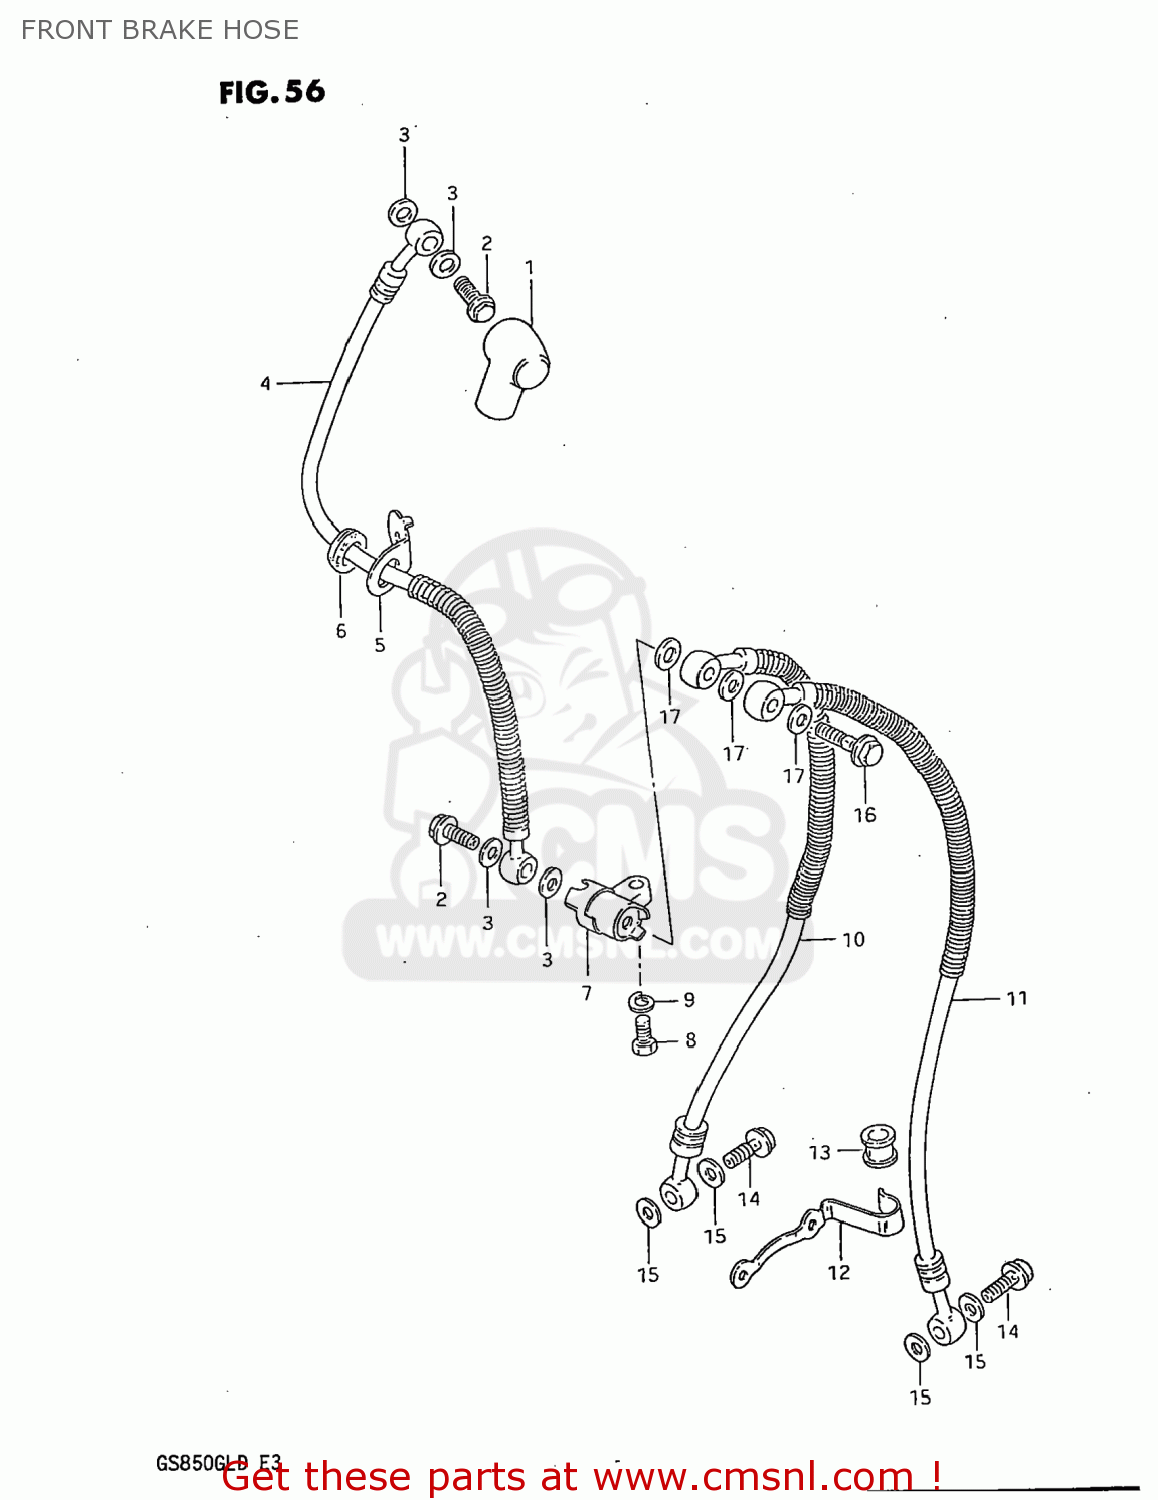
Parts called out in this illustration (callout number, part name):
1	BOOT,MASTER CYLINDER
2	BOLT,UNION
3	WASHER
4	HOSE,FRONT BRAKE NO.1
5	GUIDE,BRAKE HOSE
6	GROMMET
7	JOINT,BRAKE HOSE
8	BOLT
9	LOCK WASHER
10	HOSE,FR BRAKE NO.2,L
11	HOSE,FR BRAKE NO.2,L
12	GUIDE,BRAKE HOSE NO.2
13	BUSH,BRAKE HOSE GUIDE,NO.2
14	BOLT,UNION
15	WASHER
16	BOLT,UNION
17	WASHER
